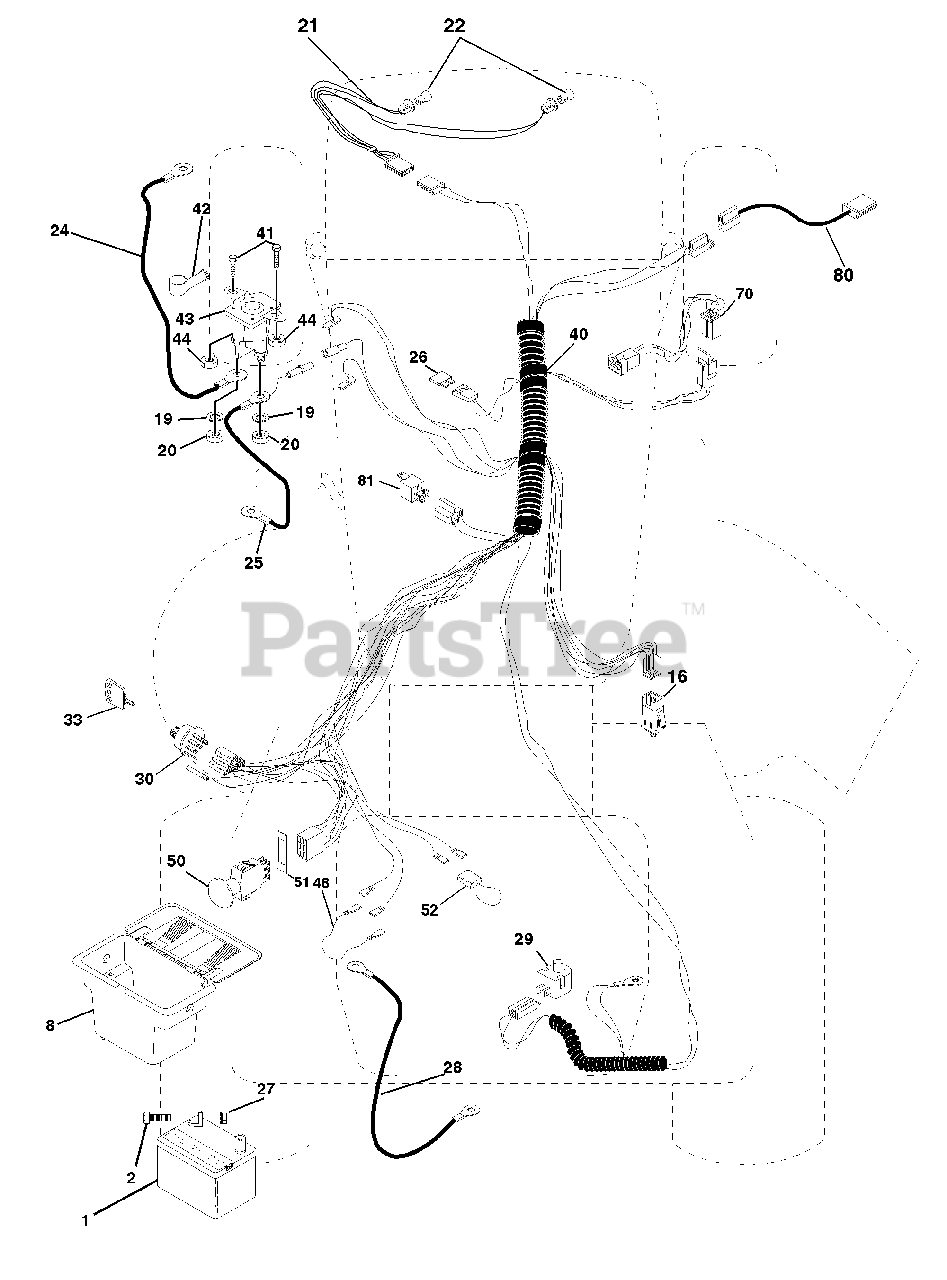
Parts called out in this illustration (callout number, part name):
1	Battery 12 Volt 25 AMP
2	Bolt Hex Hd 1/4-20unc X 3/4
8	Case Battery Mech Hinge
16	Switch Interlock Push-In
19	Washer Lock 1/4
20	Nut Jam Hex 1/4-20 Unc
21	Harness Asm Light W/4152j
22	Bulb Light #1156
24	Cable Battery 6 Ga 11" red
25	Cable Battery 6 Ga 44" red w/16 wire
26	Fuse 15 AMP
27	Nut Keps Hex 1/4-20 UNC
28	Cable Ground 6 Ga 12" black
29	Switch Plunger Normal OP Olive
30	Switch Ign 4 pos w/lights
31	Nut Ignition
32	Cover Sw Ignition
33	Key Ign Modelled Generic
40	Harness Ign.
41	Bolt Blk Fin Hex 1/4-20 x 1/2
42	Cover Terminal Red
43	Solenoid
44	Nut Keps Hex 1/4-20 Unc
48	Adapter Ammeter Rectangular
50	Switch PTO 3PDT Black Delta 96
51	Ring Retainer PTO
52	Protection Wire Loop
70	Harness, Eng. Kohl Cmd
80	Harness Clutch EVX
